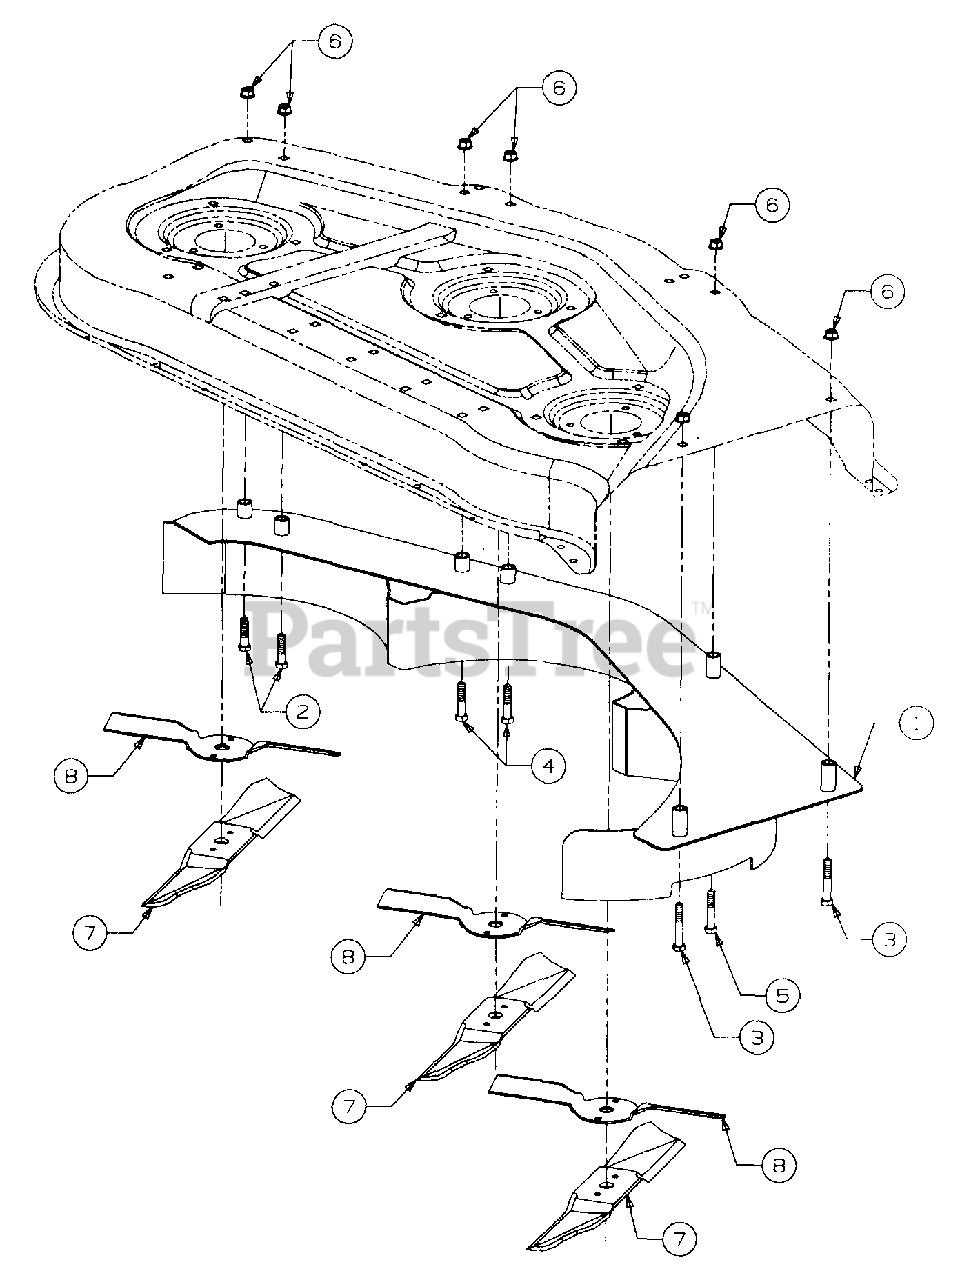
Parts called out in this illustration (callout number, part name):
3	Screw, Hex Cap, 3/8-16 x 2.25 Lg GR5
4	Screw, Hex Cap, 3/8-16 x 1.75 Lg GR5
5	Screw, Hex Cap, 3/8-16 x 2.0 Lg GR5
6	Nut, Hex Flanged Lock, 3/8-16
7	Blade, Mower, 16.5 Lg
